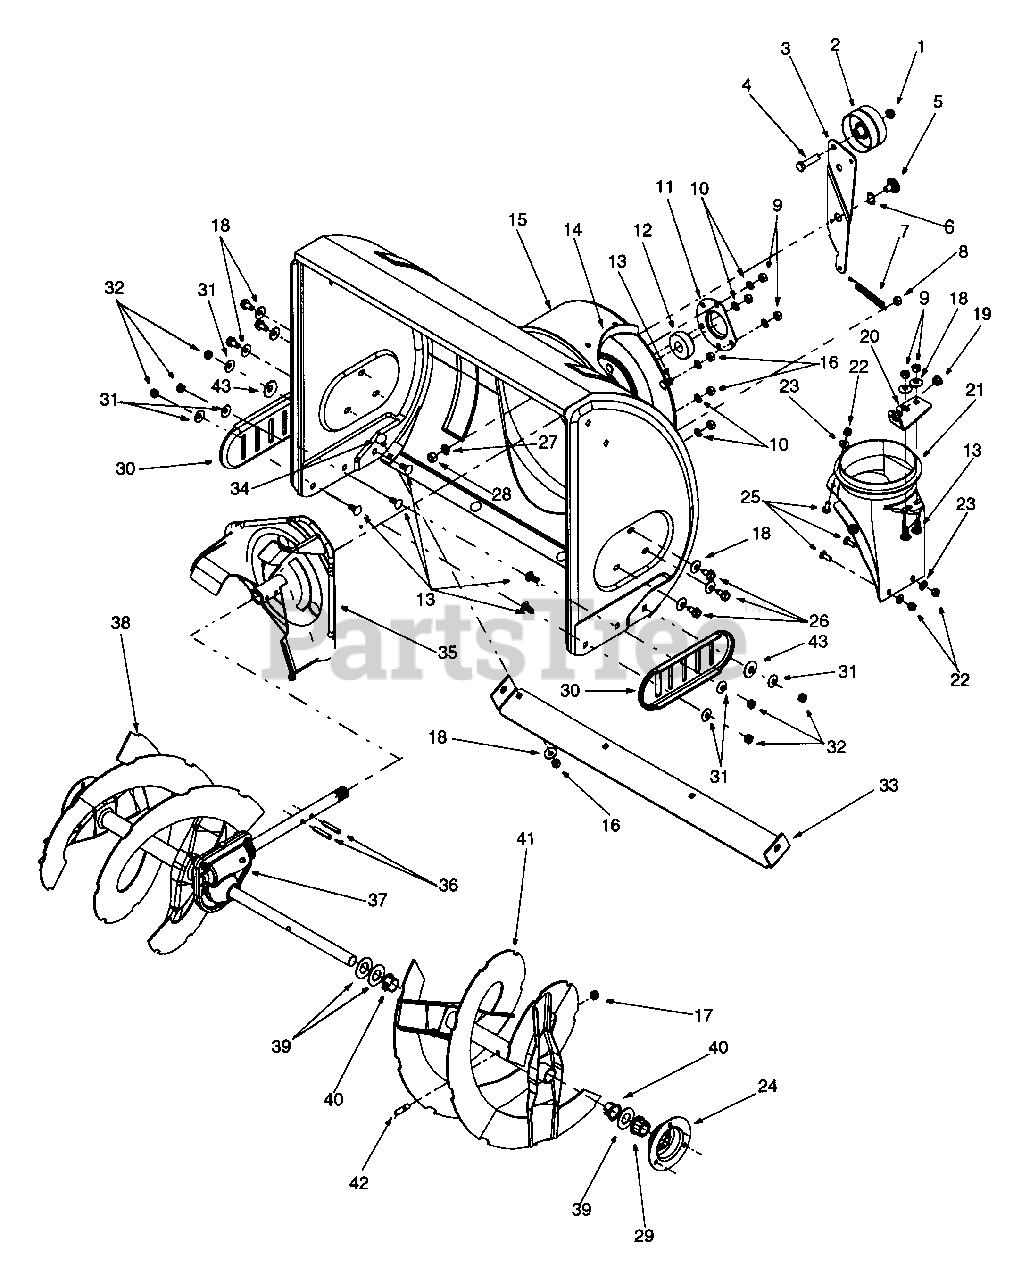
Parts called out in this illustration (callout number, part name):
1	Lock Jam Nut 3/8-24
2	Flat Idler
3	Auger Idler Arm
4	Hex Cap Screw 3/8-24 x 1.50
5	Shoulder Screw
6	Wave Washer
7	Extension Spring
8	Hex Nut 5/16-18
9	Hex Nut 5/16-18
10	Lock Washer 5/16
11	Housing
12	Ball Bearing
13	Carriage Bolt 5/16-18 x .75
17	Lock Nut 5/16-18
18	Bell Washer
19	Bushing
20	Chute Crank Bracket
21	Chute Adapter
22	Hex Lock Nut 1/4-20
23	Flat Washer
24	Bearing Housing
25	Carriage Screw 1/4-20 x .75
26	Hex Washer Screw 5/16-18
27	Lock Washer 3/8
28	Hex Nut 3/8-16
29	Hex Flange Bearing
30	Skid Shoe
31	Bell Washer
32	Hex Nut 5/16-18
33	21.66" Shave Plate
33	23.66" Shave Plate
34	Carriage Bolt 5/16-18 x .62
35	Impeller Assembly
36	Pin
37	22" Gear Assembly
37	24" Gear Assembly
38	22" Spiral RH
40	Flange Bushing
41	22" Spiral LH
41	24" Spiral LH
42	Shear Bolt 5/16-18 x 1.5
43	Flat Washer, .344 x 1.12 x .87
